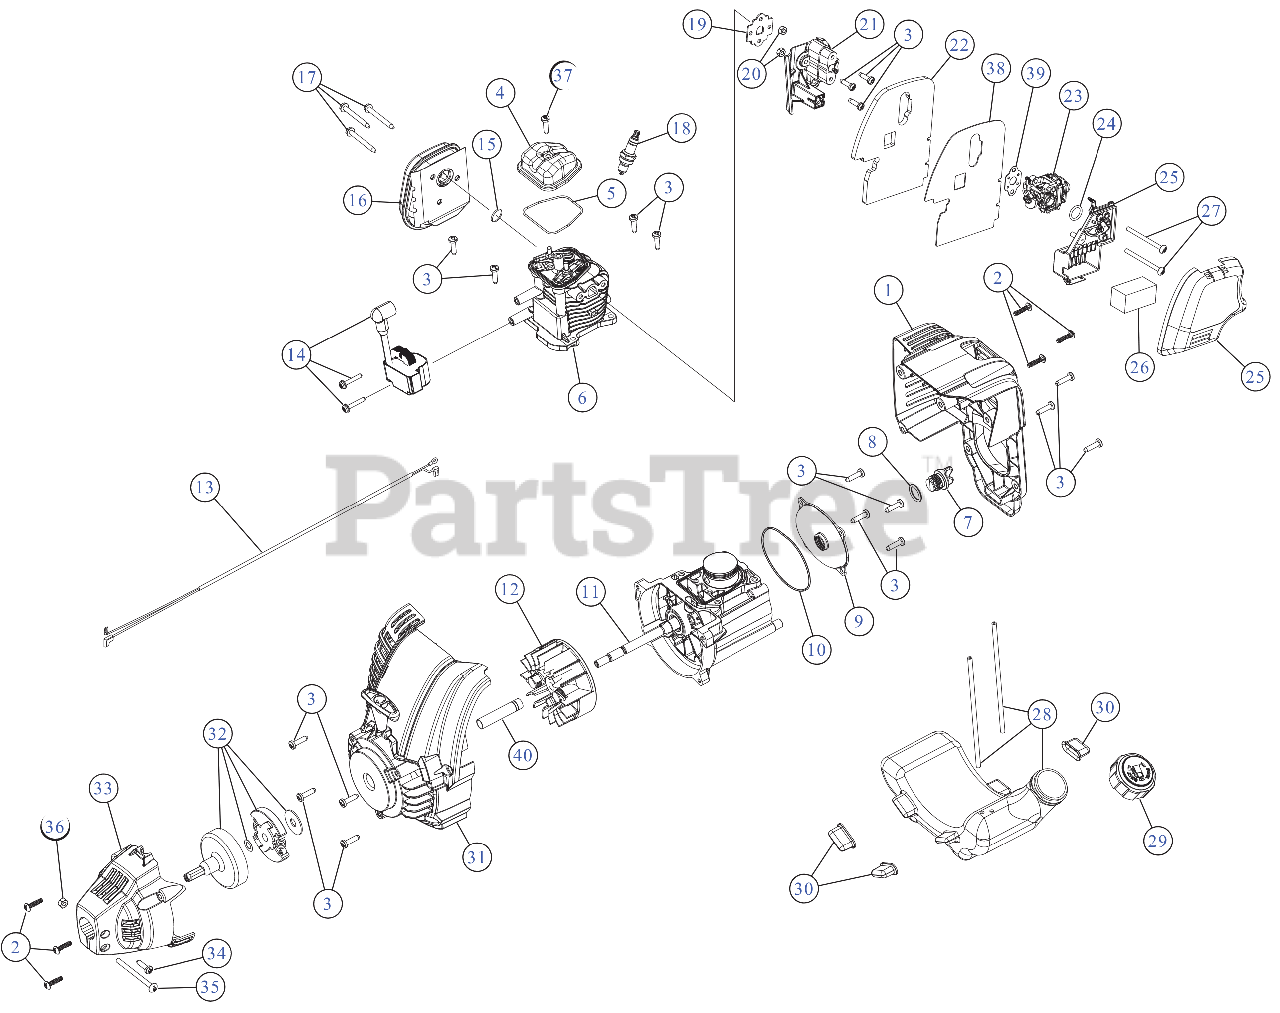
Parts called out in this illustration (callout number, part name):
1	REAR ENGINE CVR
2	SCREW 8-16 x 3/4
3	SCREW M5-0.8 x 19
4	ROCKER COVER
6	CYLINDER ASSEMBLY
7	OIL PLUG
8	RING, OIL PLUG (AC
9	CRANKCASE COVER
10	O-RING CRNKCSE CVR
11	CRANK CASE ASSEMBLY
12	FLYWHEEL ASSEMBLY AC3.1
13	WIRE LEAD TWST
14	MODULE ASSEMBLY MA-79B
15	GASKET/MUFFLER
16	MUFFLER ASSEMBLY
17	SCREW 10-32 x 1.75
18	SPARK PLUG 10MM:EM
19	GASKET/INSULATOR
21	CARB INSULATOR
22	HEAT SHIELD
23	CARBURETOR
25	AIR CLEANER COVER
26	AIR FILTER
27	SCREW 10-32X2.5
28	FUEL TANK ASSEMBLY
29	FUEL CAP ASSEMBLY 43MM-6 W/O HOLE
30	FUEL TANK PADS
31	STARTER HOUSING ASSEMBLY
32	CLUTCH ASSEMBLY
33	CLUTCH COVER ASSEMBLY
34	SCREW, 8-32 x .312 P
35	SCREW
37	SCR, VALVE COVER
39	CARBURETOR GASKET
40	SPACER :2.165"
